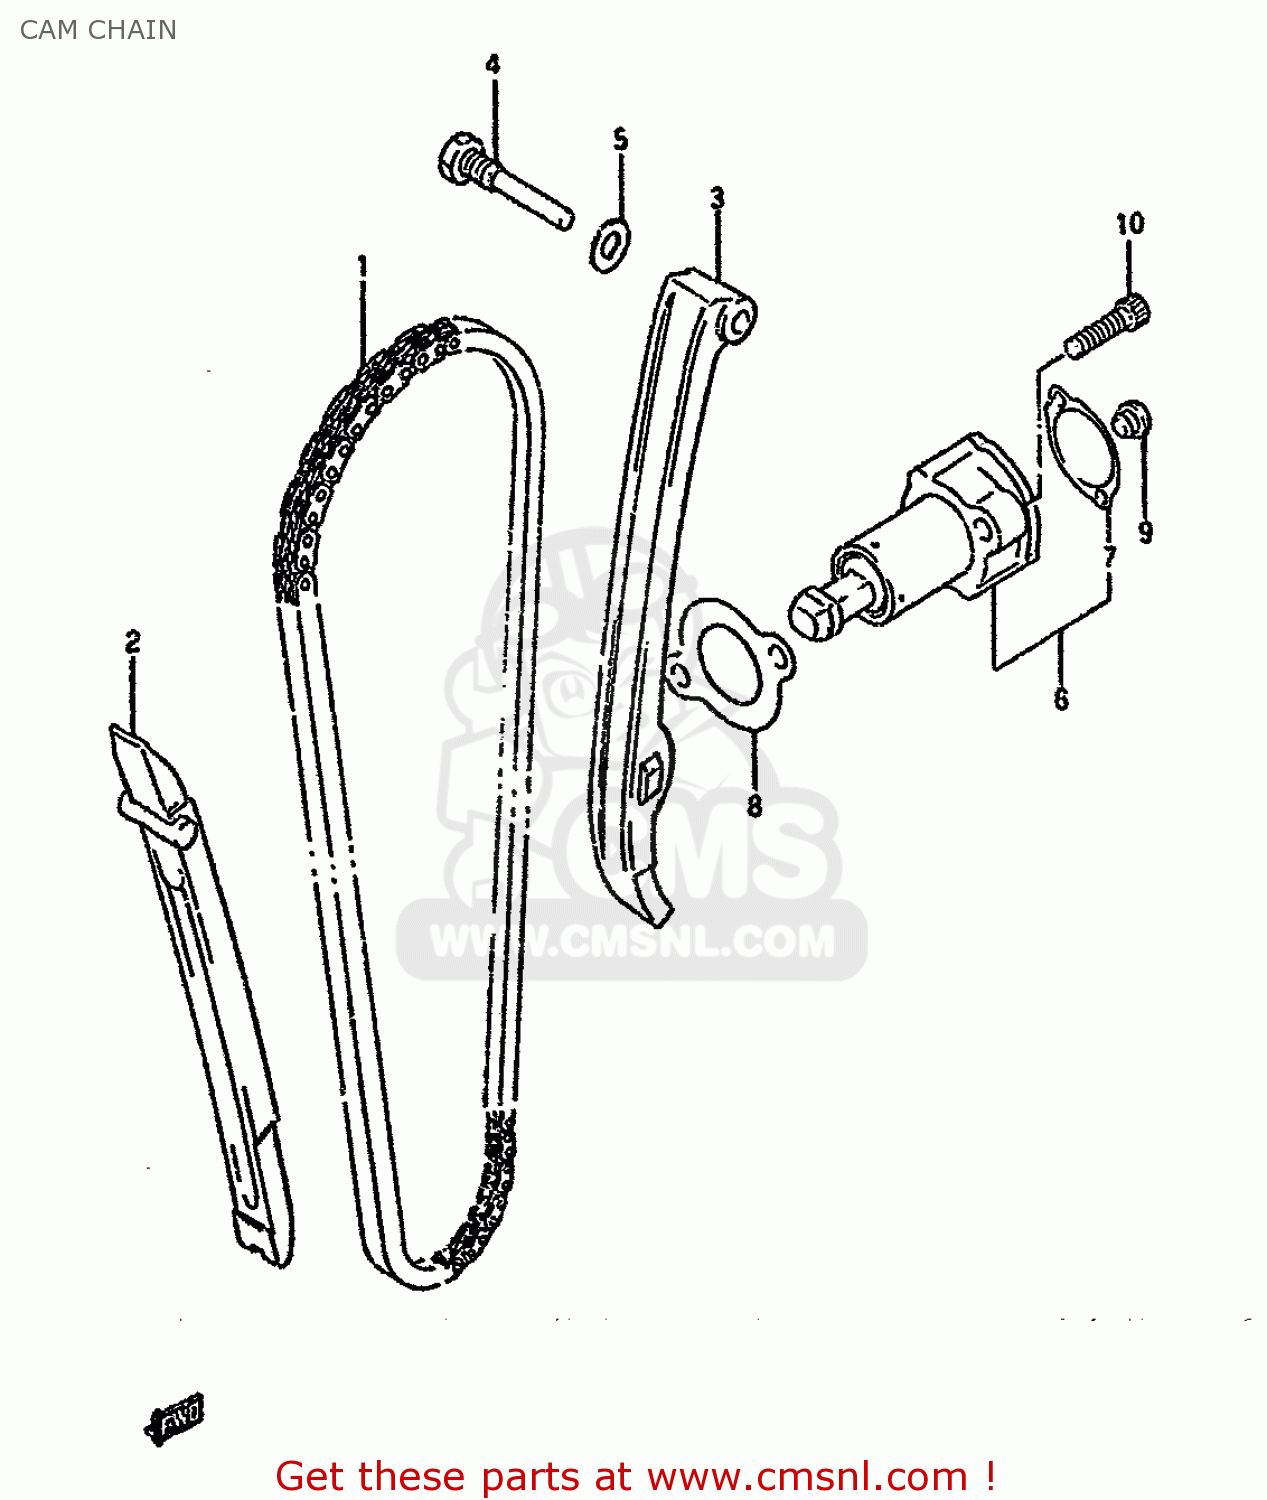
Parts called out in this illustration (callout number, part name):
1	CHAIN,CAMSHAFT DRIVE
2	GUIDE,CAM CHAIN
3	TENSIONER,CAM CHAIN
4	BOLT,CAM CHAIN TENSIONER
5	GASKET 8.2X14X1 (NAS)
6	ADJUSTER ASSY,TENSIONER
7	GASKET,ADJUSTER CAP (NAS)
8	GASKET,TENSIONER ADJUSTER (NAS)
9	PLUG,ADJUSTER
10	BOLT
